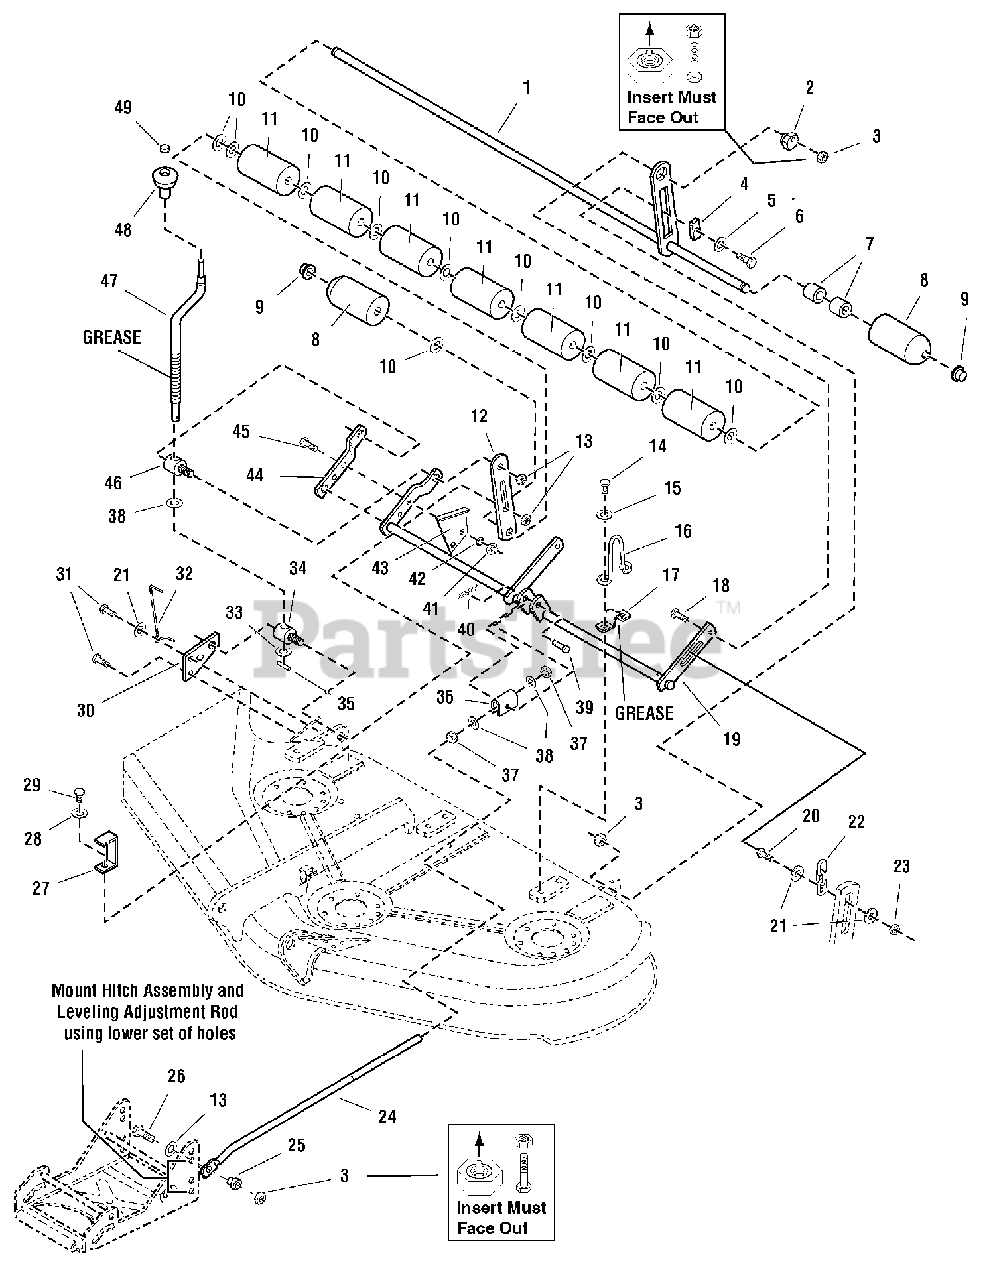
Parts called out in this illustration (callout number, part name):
1	SHAFT ASSEMBLY, Roller, 44", (Includes Ref. Nos. 7 & 9)
2	NUT, Adjuster
3	NUT, Hex Aluminum Insert Lock, 3/8-16
4	SLIDE
5	WASHER, Plain, 1/2
6	BOLT, Shoulder, 3/8-16
7	SPACER, 25/64 x 13/16 x 13/16, Steel, Black
8	ROLLER, Rounded, 2-1/2 Long
9	NUT, Push
10	WASHER, Plain, 1-1/4
11	ROLLER
12	BAR, Roller
13	NUT, Hex, Flange, Lock, 1/2-13
14	CAPSCREW, Hex Head Taptite, 5/16 -18 x 3/4
15	WASHER, 3/8
16	UP-STOP, 6-1/4 High, Black
17	STRAP, Mower Arm Assembly
18	CARRIAGE BOLT, 3/8-16 x 1-1/2
19	ARM ASSEMBLY, Mower
20	CAPSCREW, Hex Head, 5/16-18 x 1 1/2, Black
21	WASHER, 5/16, Black
22	CHAIN, 3 Link, 4-1/2 Long
23	NUT, Hex Lock ESNA Light, 5/16-18
24	ROD, Adjustment
25	SPACER, 3/8 x 3/4 x 15/16
26	CAPSCREW, Hex Head, 3/8-16 x 1-3/4
27	BRACKET, Up-Stop, 6" Long
28	WASHER, 5/8
29	CAPSCREW, Hex Washer Head Taptite, 5/16-18 x 1, Black
30	PLATE, Mower Support
31	CAPSCREW, Hex Head Taptite, 5/16-18 x 1-1/4
32	INDICATOR, Cutting Height
33	WASHER, Detent
34	TRUNNION
35	PIN, Roll, 1
36	TRUNNION
37	NUT, Hex, Jam, 1/2-13
38	WASHER, 33/64
39	PIN, Clevis
40	CLIP, Hair Pin
41	NUT, Hex, 5/16-18
42	WASHER, Lock, 5/16
43	BRACKET, Cutting Height
44	ARM, Rear, Mower, RH
45	CAPSCREW, Hex Head, 5/16-18 x 1-1/4
46	TRUNNION, Threaded
47	CRANK, Cutting Height
48	KNOB, Height Crank
49	PAL NUT
